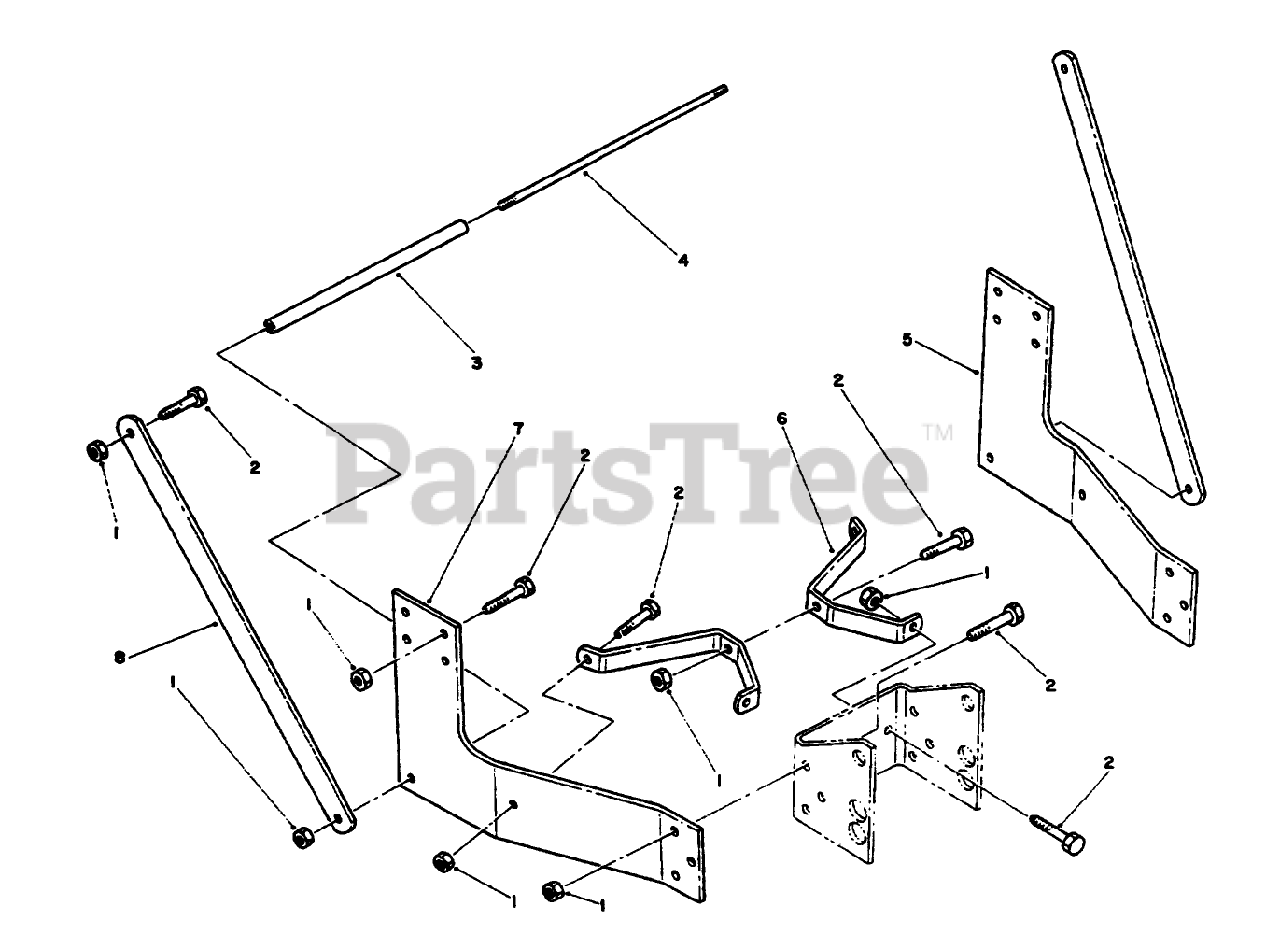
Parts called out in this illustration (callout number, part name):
1	NUT-LOCK, NI
2	SCREW-HH
3	SUPPORT TUBE
4	SUPPORT ROD
